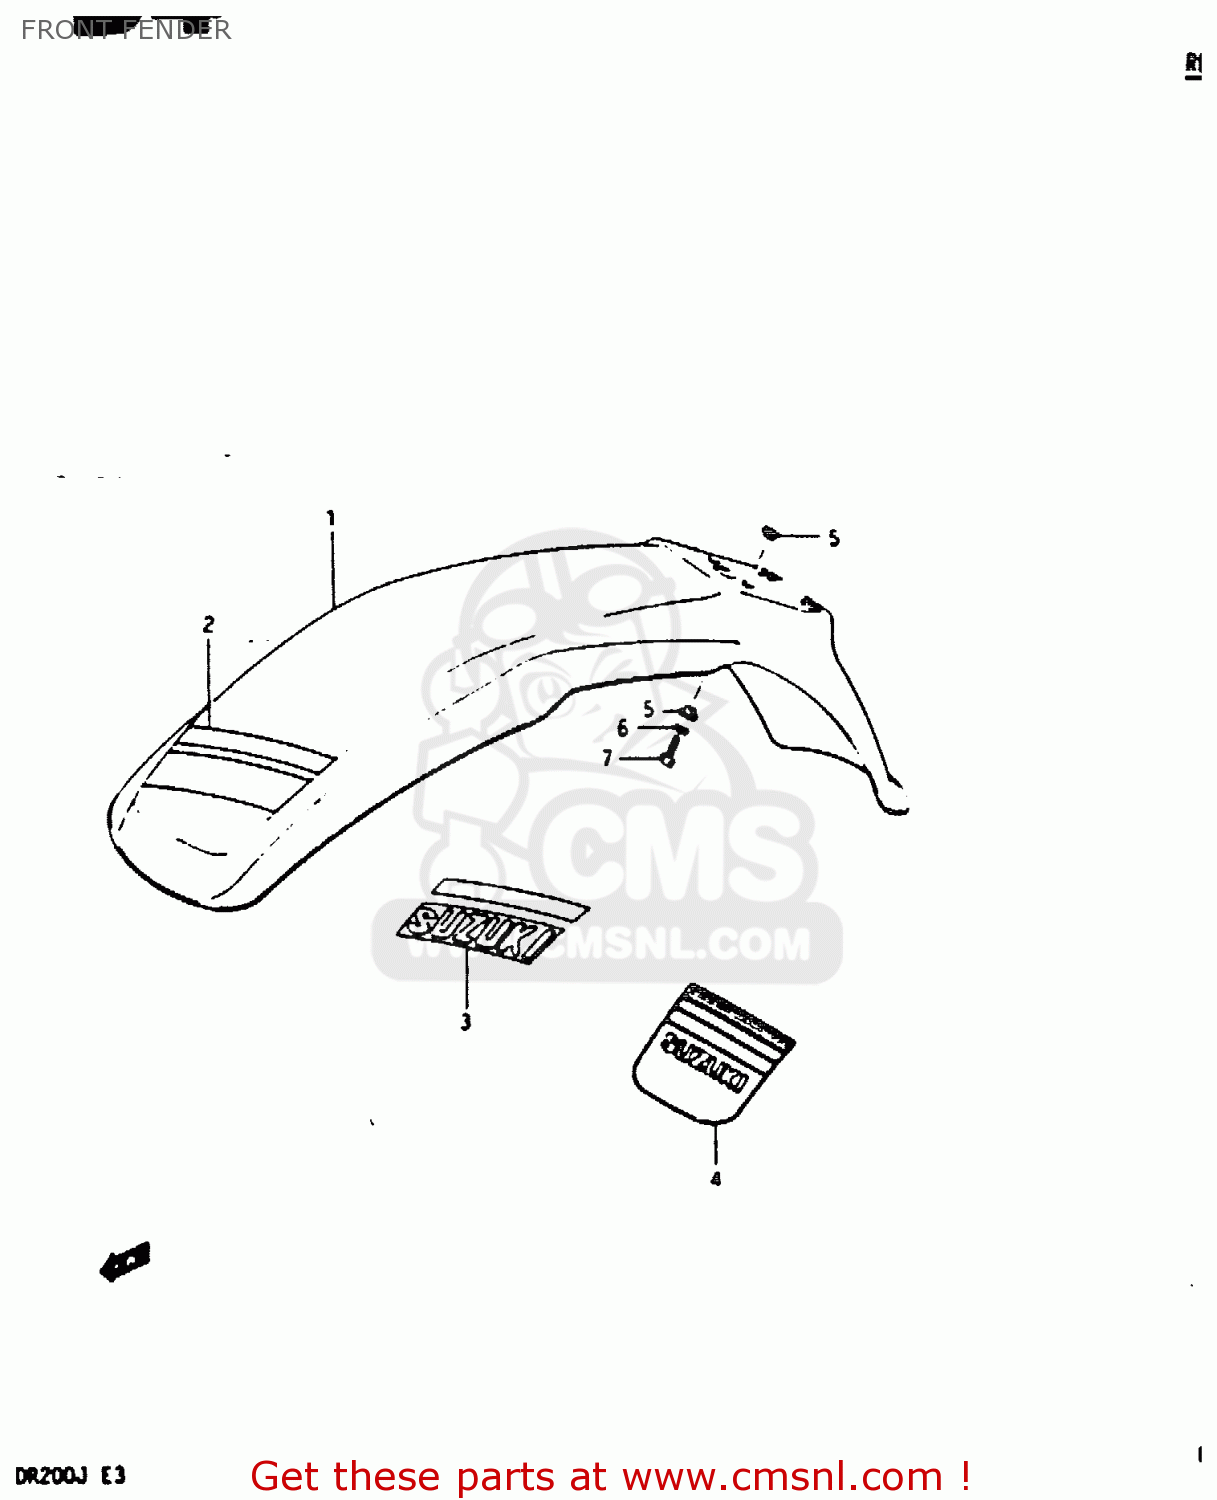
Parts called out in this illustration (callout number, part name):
1	FENDER,FRONT
2	TAPE SET,FRONT FENDER
3	TAPE,FRONT FENDER
4	TAPE,FRONT FENDER
5	WASHER
6	WASHER,LOCK
7	BOLT
